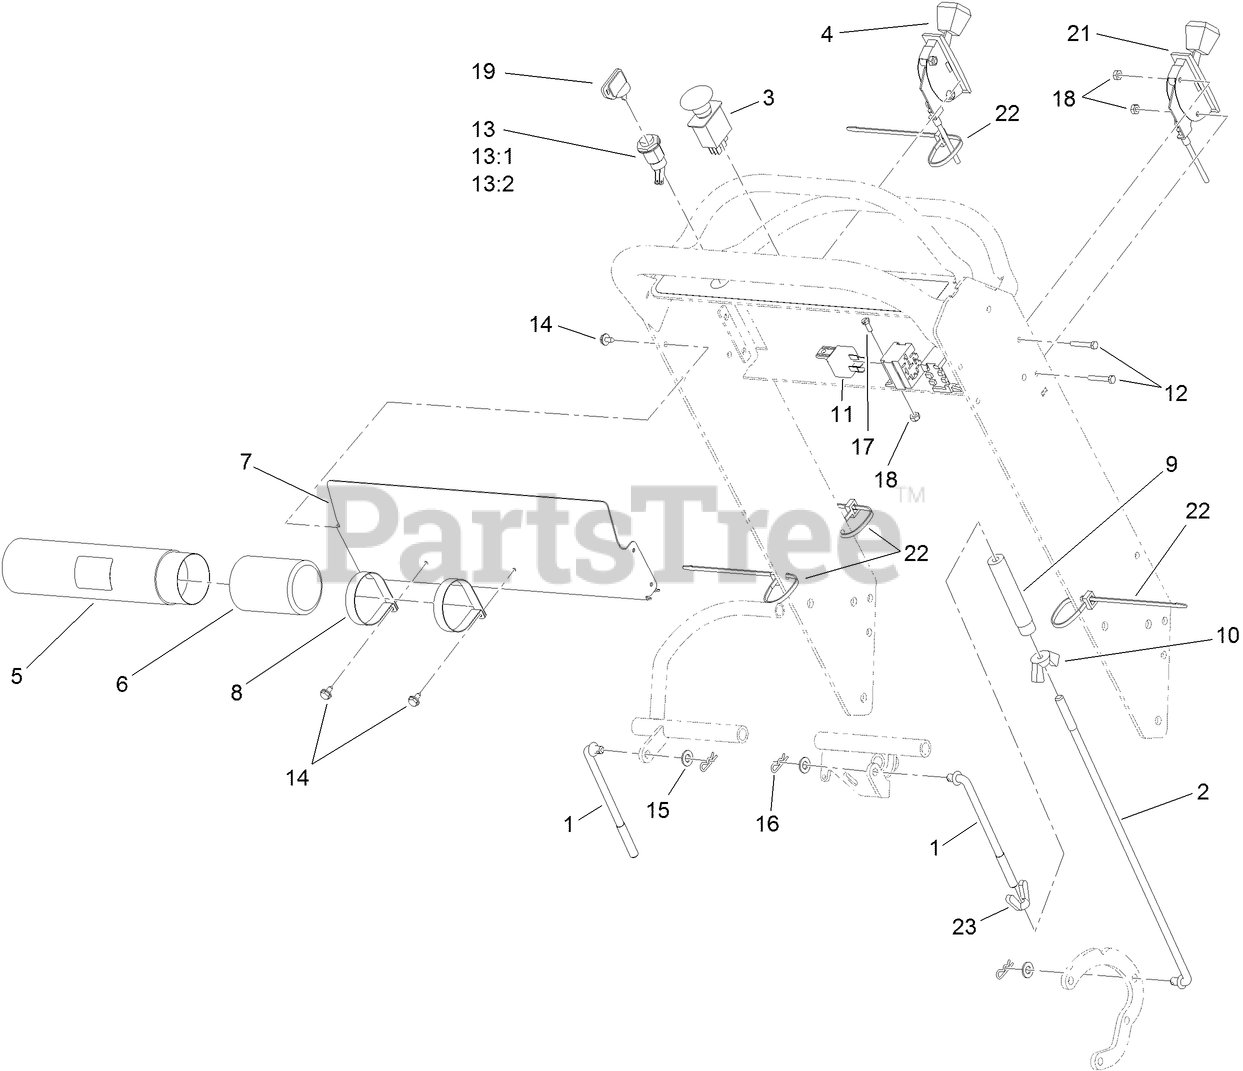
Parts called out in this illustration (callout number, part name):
1	ROD-CONTROL, UPPER
2	ROD-CONTROL, LOWER
3	SWITCH-PTO, ON-ON-(ON)
4	CABLE-THROTTLE
5	TUBE-MANUAL
6	CAP-HOUSING
7	COVER-PANEL, CONTROL
8	CLAMP-R
9	TURNBUCKLE
10	NUT-WING
12	SCREW-HH
13	SWITCH-ON / OFF
13:1	NUT-HH
13:2	WASHER-TOOTH, INTERNAL
14	SCREW-HWHTF
15	WASHER-PLAIN
16	PIN-COTTER
17	SCREW-SHH
18	NUT-LOCK, NI
19	KEY-IGNITION
21	CABLE-CHOKE
22	TIE-CABLE
23	NUT-WING, LH
